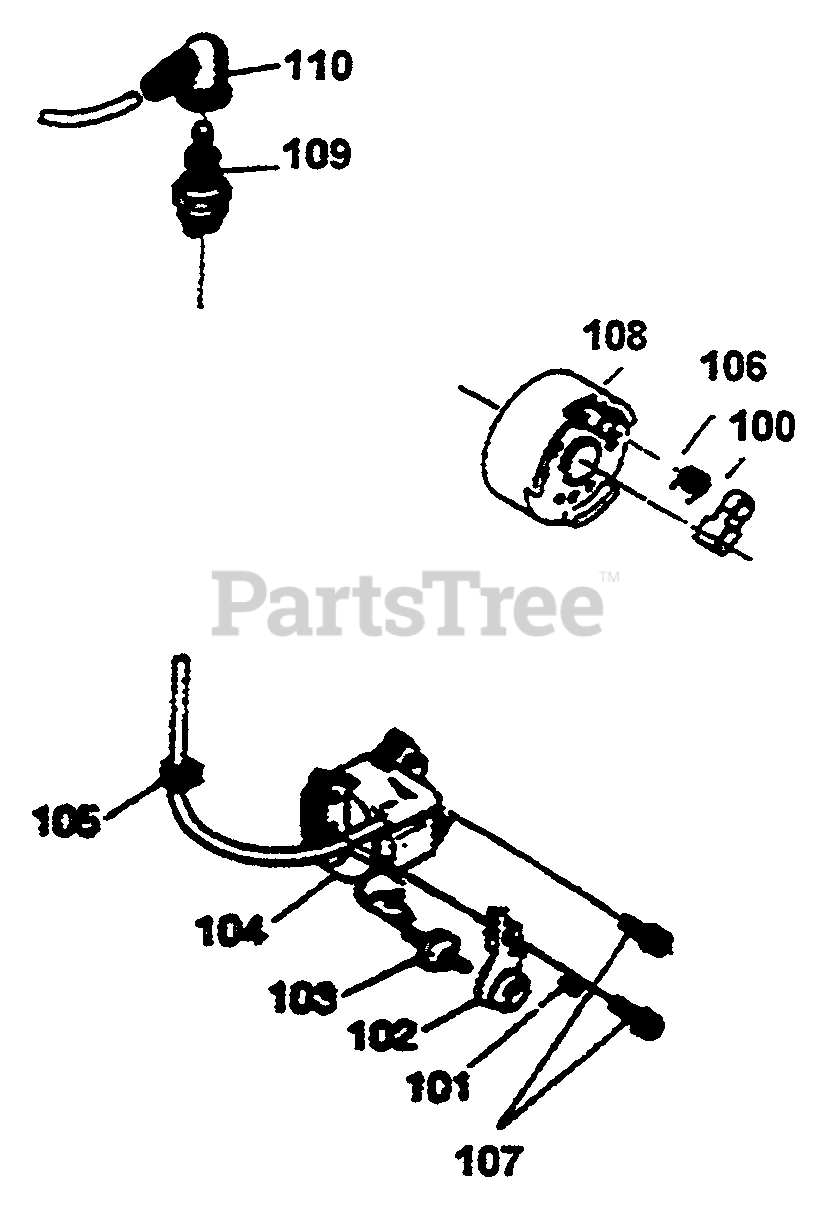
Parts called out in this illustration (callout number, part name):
103	SWITCH, STOP
104	COIL, IGNITION
106	SPRING, RETURN
107	BOLT & WASHER
109	SPARK PLUG
110	CAP, PLUG
